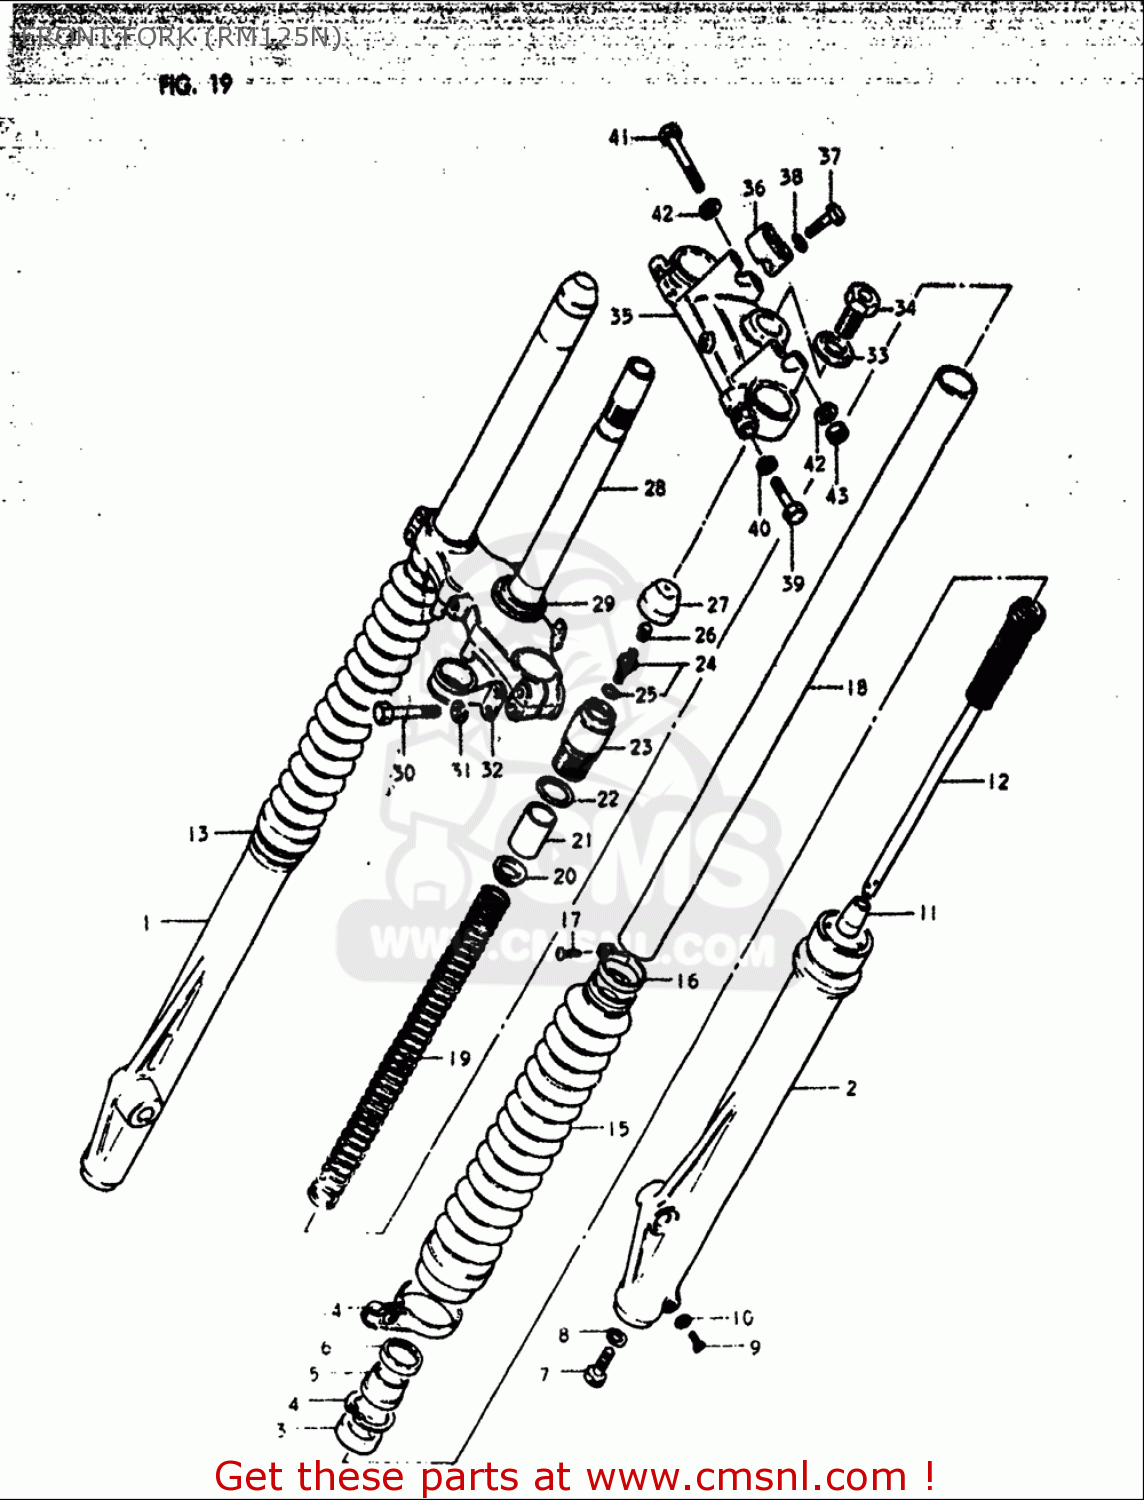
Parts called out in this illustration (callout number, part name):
3	SEAL,OIL
5	SEAL,DUST
7	BOLT,CYLINDER
8	GASKET,CYLINDER (NAS)
9	SCREW
10	GASKET,DRAIN,PLUG (NAS)
15	BOOT
16	BAND,BOOT
17	SCREW
20	GUIDE
22	O RING
24	VALVE
25	O RING
26	CAP,VALVE AIR
27	CAP
30	BOLT
31	WASHER,LOCK
32	CLIP,CABLE
33	WASHER
34	BOLT
36	HOLDER,HANDLEBAR
37	BOLT
38	WASHER,LOCK
39	BOLT
40	WASHER,LOCK
41	BOLT
42	WASHER
43	NUT
